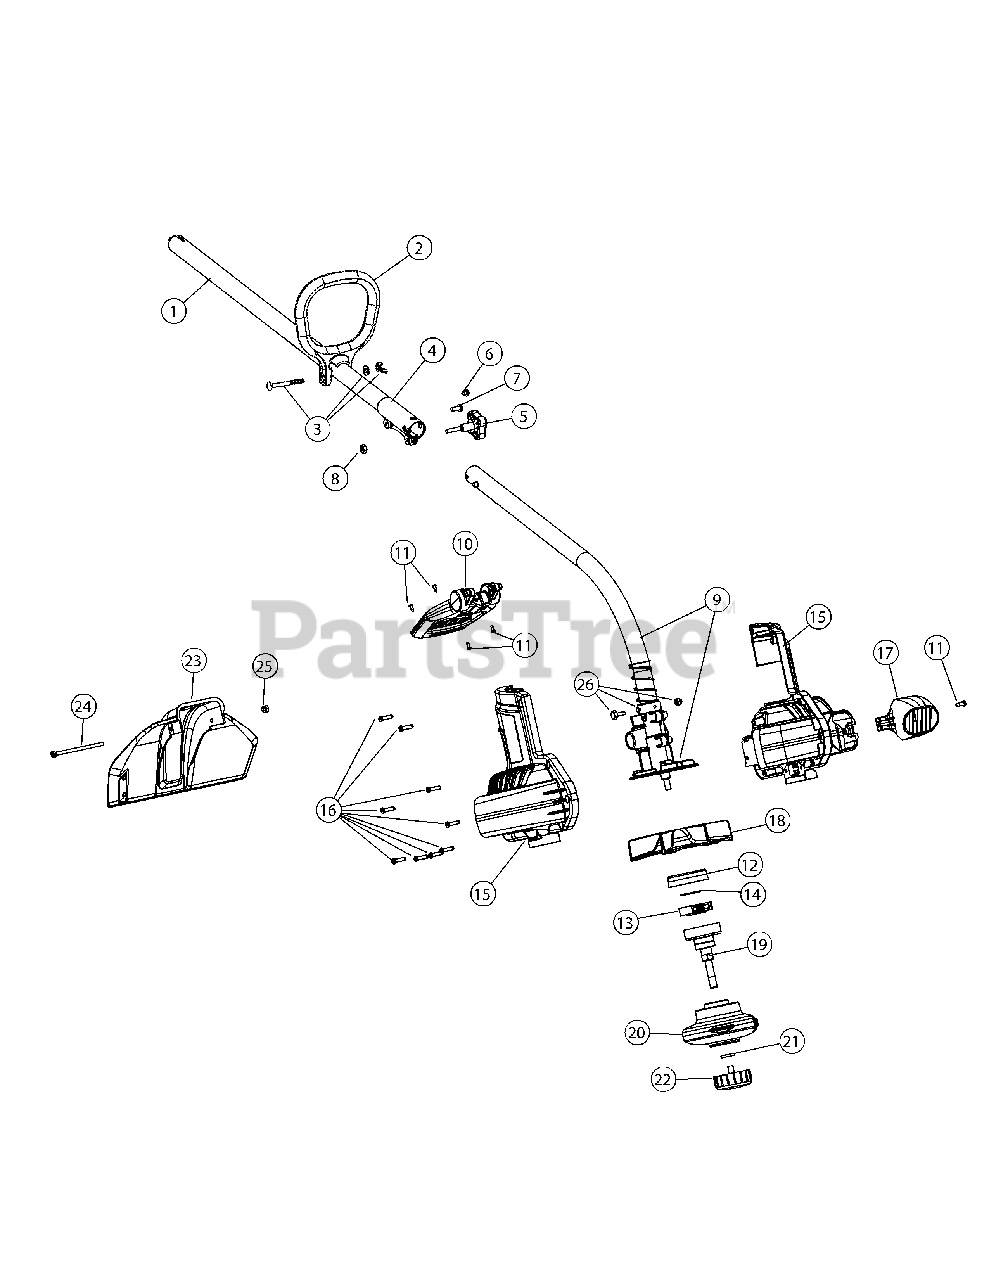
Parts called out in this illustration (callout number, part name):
1	Upper Drive Shaft Housing Assembly
2	D-Handle
3	D-Handle Hardware Assembly
4	Split Boom Coupler
5	Adjustment Knob
8	Nut
9	Lower Drive Shaft Housing Assembly
10	Handle Shift Assembly
11	Screw
12	Clutch Drum Container
13	Clutch Assembly
14	Washer
15	Housing Assembly
16	Screw
17	Nozzle
18	Impeller
19	Clutch Drum Assembly w/Spool Shaft
20	Fixed Line Head
21	Lock Washer
22	Bump Head Knob Assembly
23	Guard Assembly w/Blade
24	Screw
25	Nut
